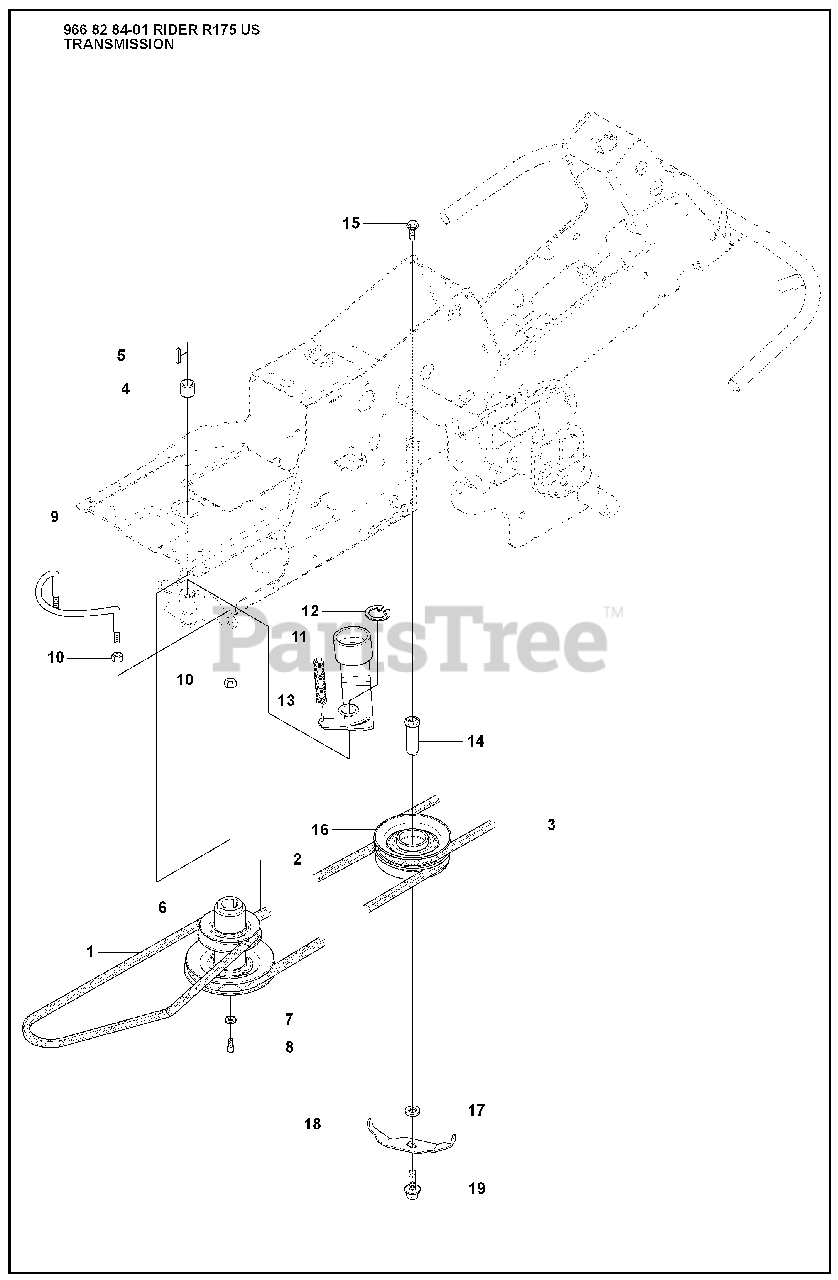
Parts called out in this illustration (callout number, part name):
1	BELT
2	BELT
3	BELT
9	Belt Guide
10	NUT
12	RETAINING RING SGA 25
14	SHAFT
18	BELT GUIDE
19	BOLT
